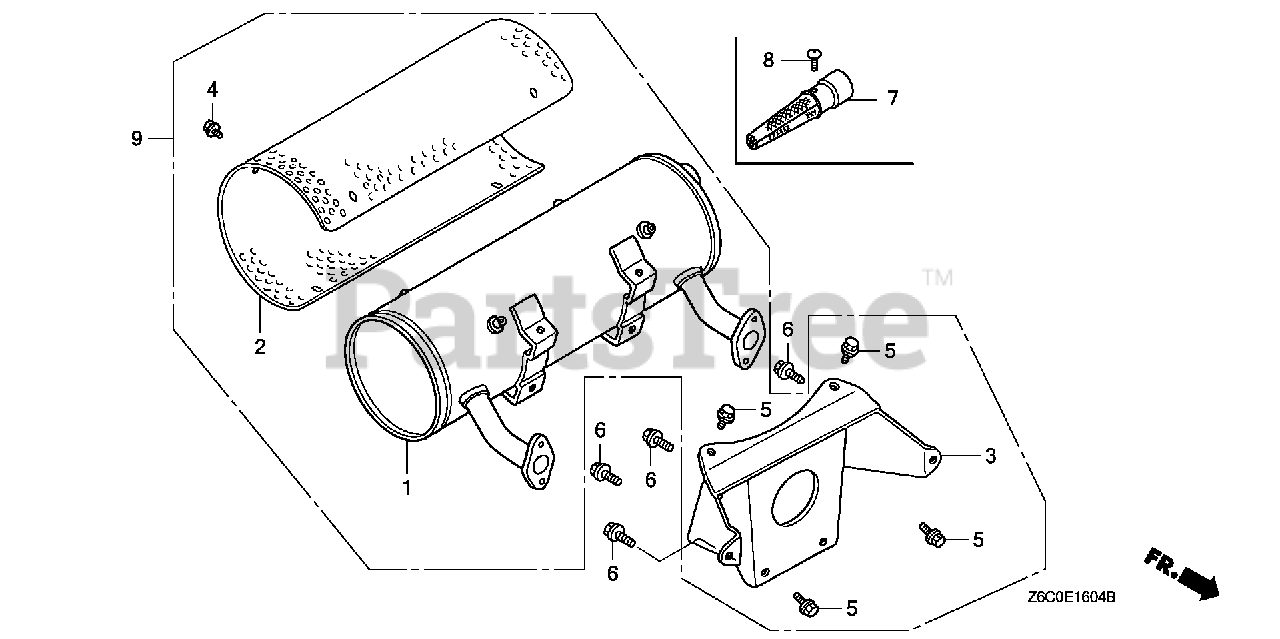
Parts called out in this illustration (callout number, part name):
1	MUFFLER COMP. (HIGH-L) (FUTABA) (SILVER MUFFLER) (FOR SILVER MUFFLER)
2	PROTECTOR, MUFFLER (HIGH) (FUTABA) (FOR BLACK MUFFLER)
3	STAY, MUFFLER (HIGH-FUTABA) (FOR SILVER MUFFLER)
4	BOLT, FLANGE (6X8)
5	BOLT, FLANGE (8X14)
6	BOLT, FLANGE (8X20) Use up to Engine SN 1609606.
7	ARRESTER KIT (HIGH)
7	ARRESTER, SPARK (FOR SILVER MUFFLER)
8	SCREW, TAPPING (5X8) (FOR SILVER MUFFLER)
